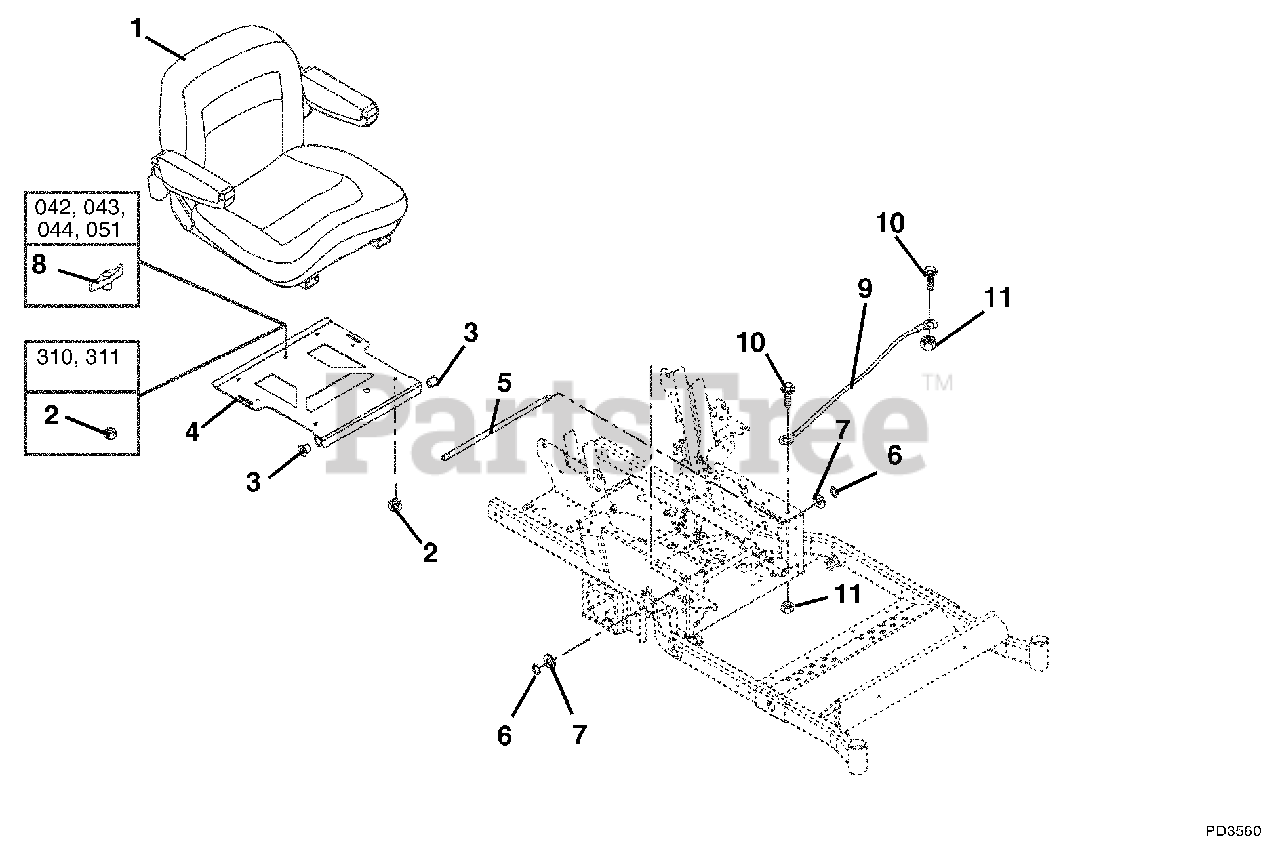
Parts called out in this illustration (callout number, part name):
2	Nut-Locking-Top-Flange .31-18 (042, 043, 044, 051, 054, 055)
2	Nut-Locking-Top-Flange .31-18 (310, 311)
3	Bushing-Flange .515 x .750 x .745 x 1.00
4	Seat Pivot Mount
5	Rod, Seat Frame Pivot
6	Ring-Retaining-External .500 x .050
7	Washer-Flat-Steel .531 x 1.06 x .095
8	Knob- Wing .312-18 (042, 043, 044, 051, 054, 055)
9	Cable, Hood
10	Bolt-Hex .25-20 x .75 Grade 5
11	Nut-Locking-Top-Flange .25-20
